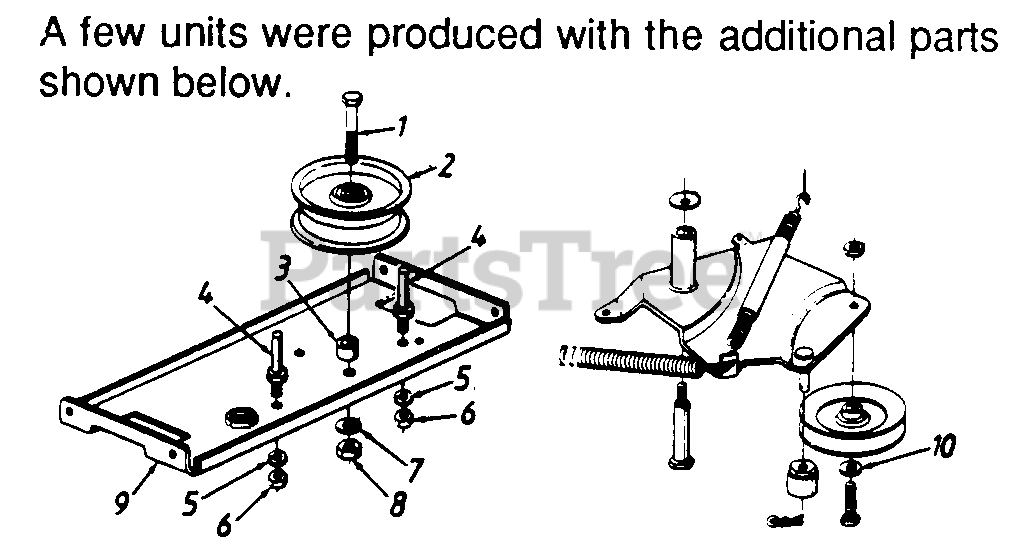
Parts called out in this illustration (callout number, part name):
1	Hex Bolt 3/8-24 x 2' Lg.
2	Fl-Idler 4" O.D.
3	Spacer .375" I.D. x .625' O.D.
4	Belt Guard Pin 1/4-20 Thd.
5	L-Wash. 1/4" I.D.
6	Hex Nut 1/4-20 Thd.
7	L-Wash. 3/8' I.D.
8	Hex Nut 3/8 24 Thd.
10	Fl-Wash. .406' I.D. x 1 1/4' O.D.
